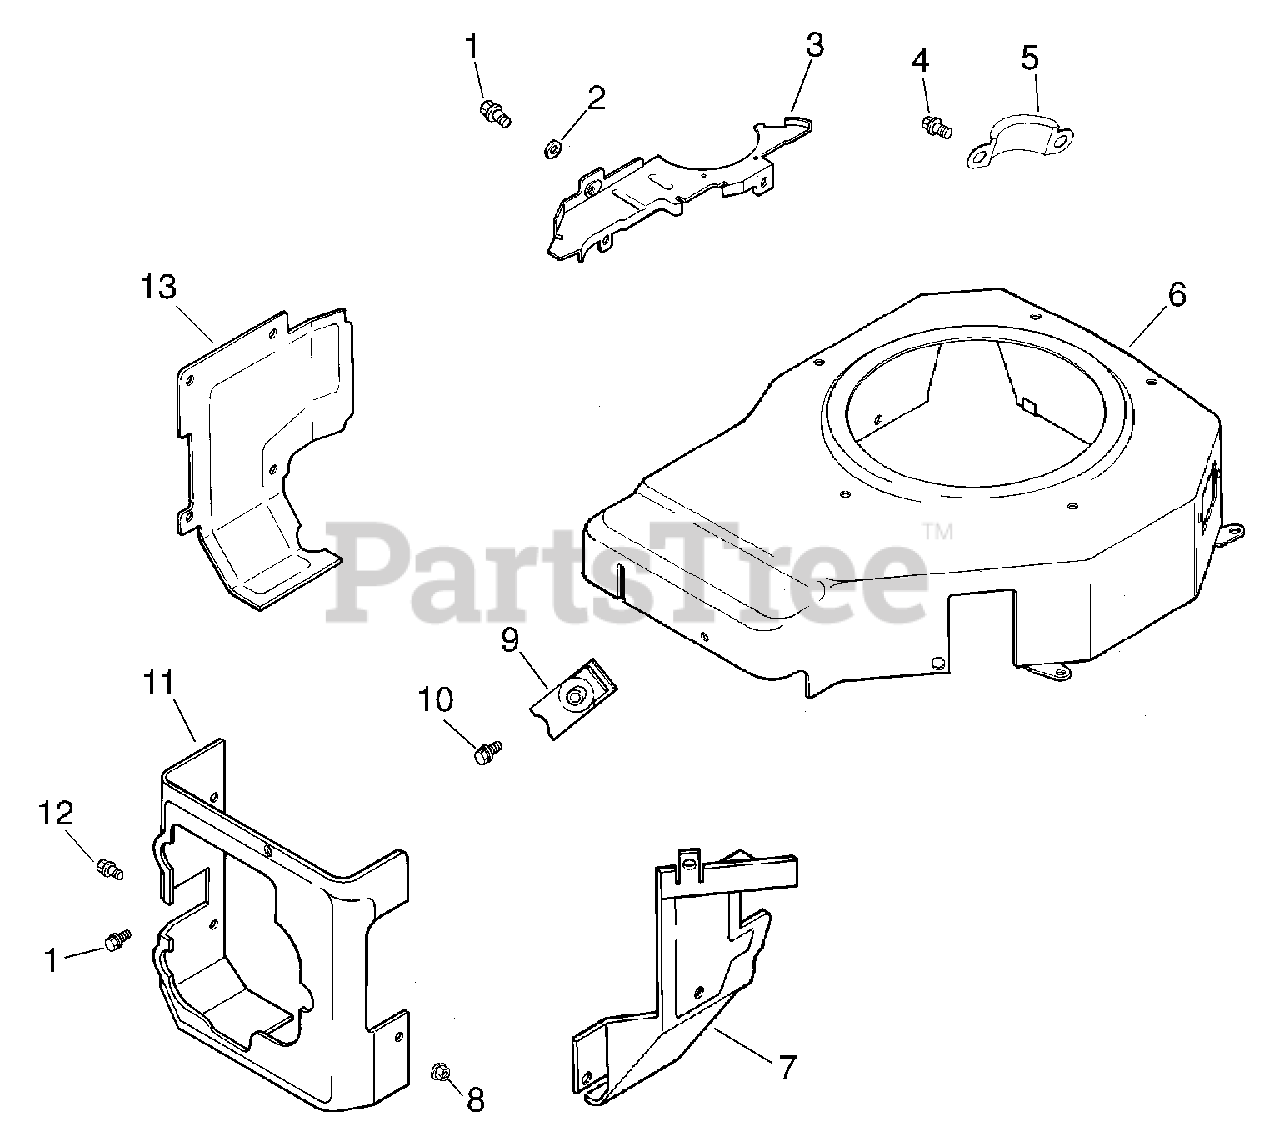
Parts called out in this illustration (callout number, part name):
1	Screw, Hex. Flange M5 x 0.8 x 10
2	Washer, Plain 1/4"
3	Plate, Blower Housing
4	Screw, Hex. Flange M5 x 0.8 x 10
5	Cover, Pinion
6	Housing, Blower
7	Baffle, Intake Side
8	Nut, Hex. Flange M5 x 0.8 (Model 1517)
9	Clip, Mounting
10	Screw, Hex. Flange M6 x 1.0 x 16
11	Baffle, Cylinder Head
12	Screw, Captive Washer M5 x 0.8 x 20
13	Baffle, Cylinder
